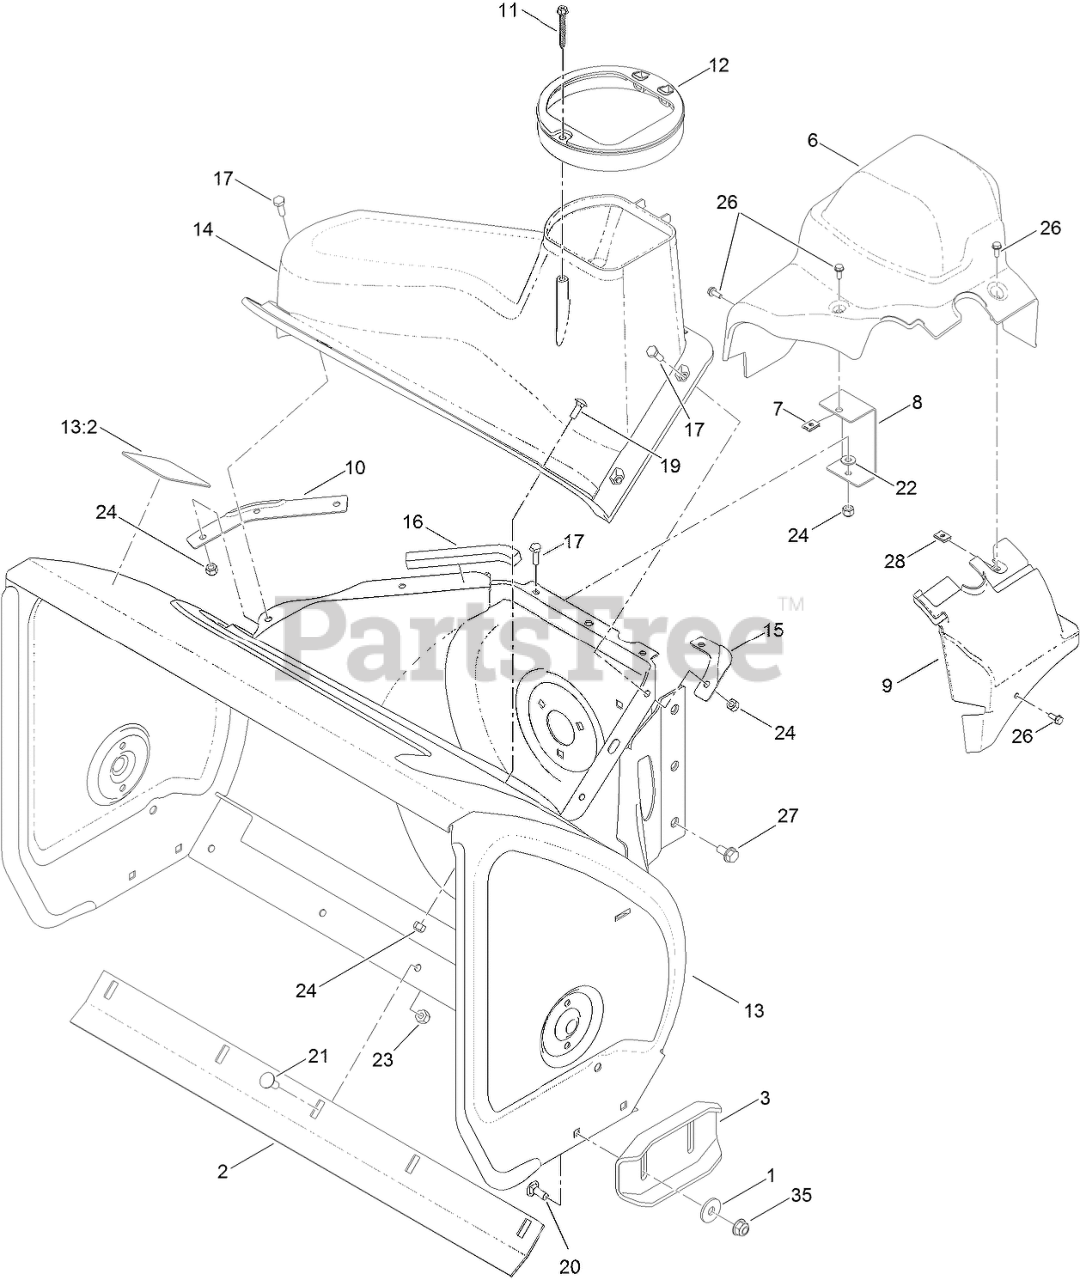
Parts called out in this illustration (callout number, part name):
1	WASHER
2	SCRAPER-FIXED
6	COVER-BELT
7	NUT-SPEED, U-TYPE
8	BRACKET-COVER, CLIP NUT
9	COVER-EXTENSION, BELT
10	SEAL-FLANGE, COVER
11	SCREW-HWH, PLASTITE
12	GUIDE-CHUTE
13	HOUSING-AUGER, 26 INCH
13:2	DECAL-DANGER, AUGER
16	SEAL-HOUSING
17	SCREW-HH
19	BOLT-CARR
20	SCREW-CARR
21	SCREW-CARR
22	WASHER-FLAT
23	NUT-LOCK, NI
24	NUT-LOCK, NI
26	SCREW-HWH
27	SCREW-HWHTF
28	NUT-SPEED
35	NUT-HF, NI
